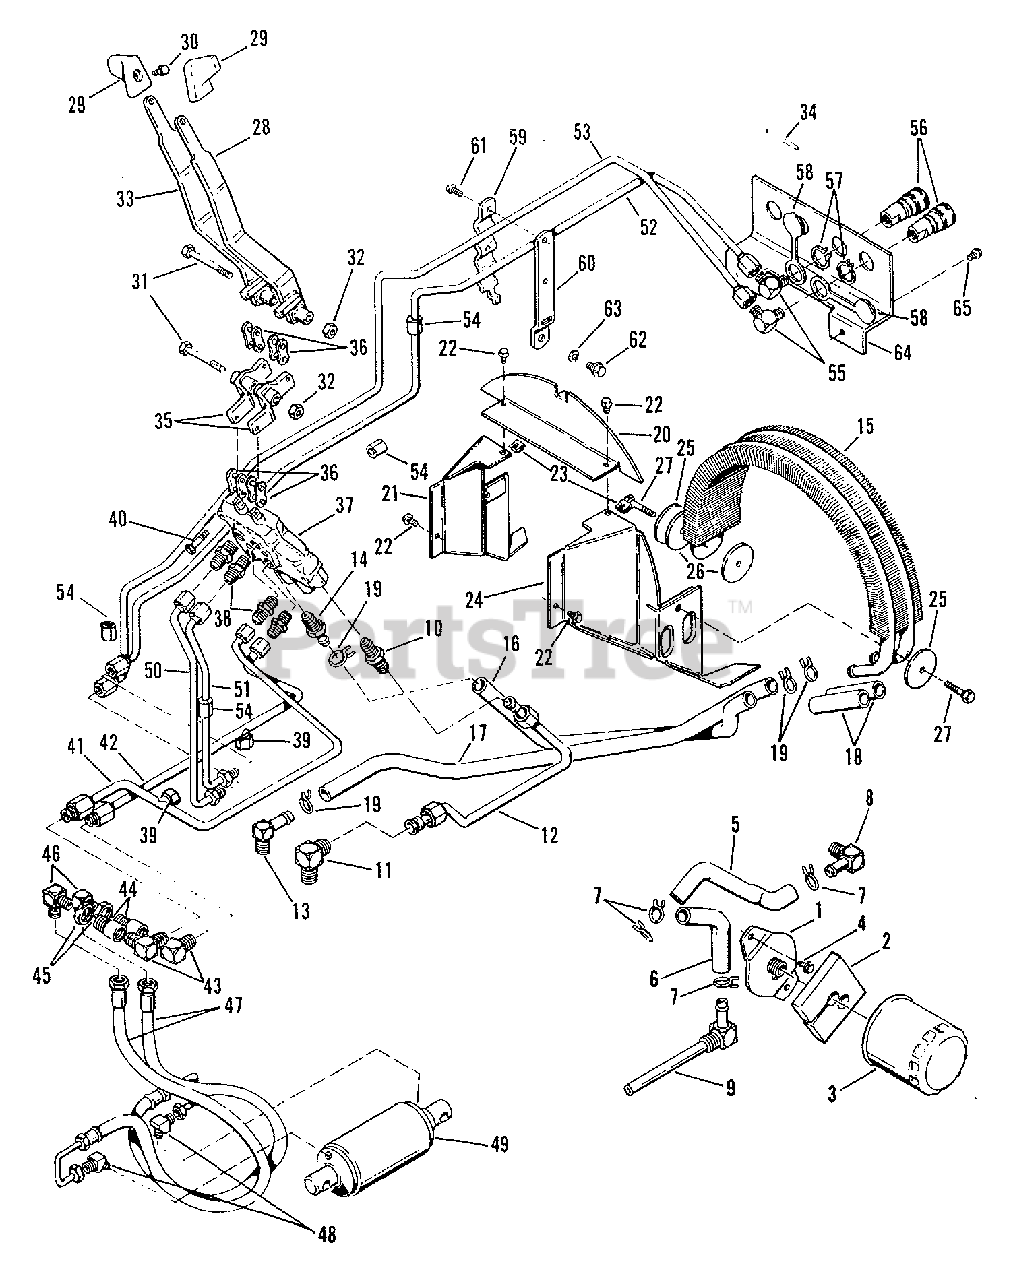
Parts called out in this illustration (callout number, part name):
1	FILTER PLATE ASSEMBLY
3	FILTER, Oil
4	CAPSCREW, Hex, 5/16-18 x 1/2" Lg.
5	HOSE, Hydraulic
6	HOSE, Hydraulic
7	CLAMP, Hose
8	ELBOW, 90 Degrees
9	ELBOW, 90 Degrees
10	CONNECTOR, Male
11	ELBOW, 90 Degrees
12	TUBE ASSEMBLY
13	ELBOW, 90 Degrees
14	CONNECTOR, Hose
15	COOLER, Oil
16	HOSE, Hydraulic
17	HOSE, Hydraulic
18	HOSE, Hydraulic
19	CLAMP, Hose
20	UPPER SHROUD, Rear
21	SHROUD ASSEMBLY, L.H.
22	SCREW, Thread Forming, 1/4"-20 x 3/8" Lg.
23	NUT, Speed
24	SHROUD ASSEMBLY, R.H.
27	SCREW, Thread Forming, 1/4"-20 x 1-1/2" Lg.
28	LEVER ASSEMBLY
30	SCREW, Thread Forming, 1/4"-20 x 3/4" Lg.
31	CAPSCREW, Hex, 3/8"-16 x 2-3/4" Lg.
32	NUT, Hex, Jam 3/8"-16
33	LEVER ASSEMBLY
34	FILM, "Power Lift"
35	BELLCRANK ASSEMBLY
36	LINK, Connector
37	VALVE, Hydraulic
38	CONNECTOR, Male
40	CAPSCREW, Hex, 1/4"-20 x 1-3/4" Lg.
41	TUBE ASSEMBLY
42	TUBE ASSEMBLY
50	TUBE ASSEMBLY
51	TUBE ASSEMBLY
52	TUBE ASSEMBLY
53	TUBE ASSEMBLY
56	BODY ASSEMBLY
57	RING, Retaining
58	PLUG, Plastic
61	SCREW, Taptite, 1/4"-20 x 5/8" Lg.
62	CAPSCREW, Hex, 3/8"-16 x 5/8" Lg.
63	LOCKWASHER, 3/8"
64	PLATE, Mounting
65	SCREW, Washer Head, 1/4"-20
